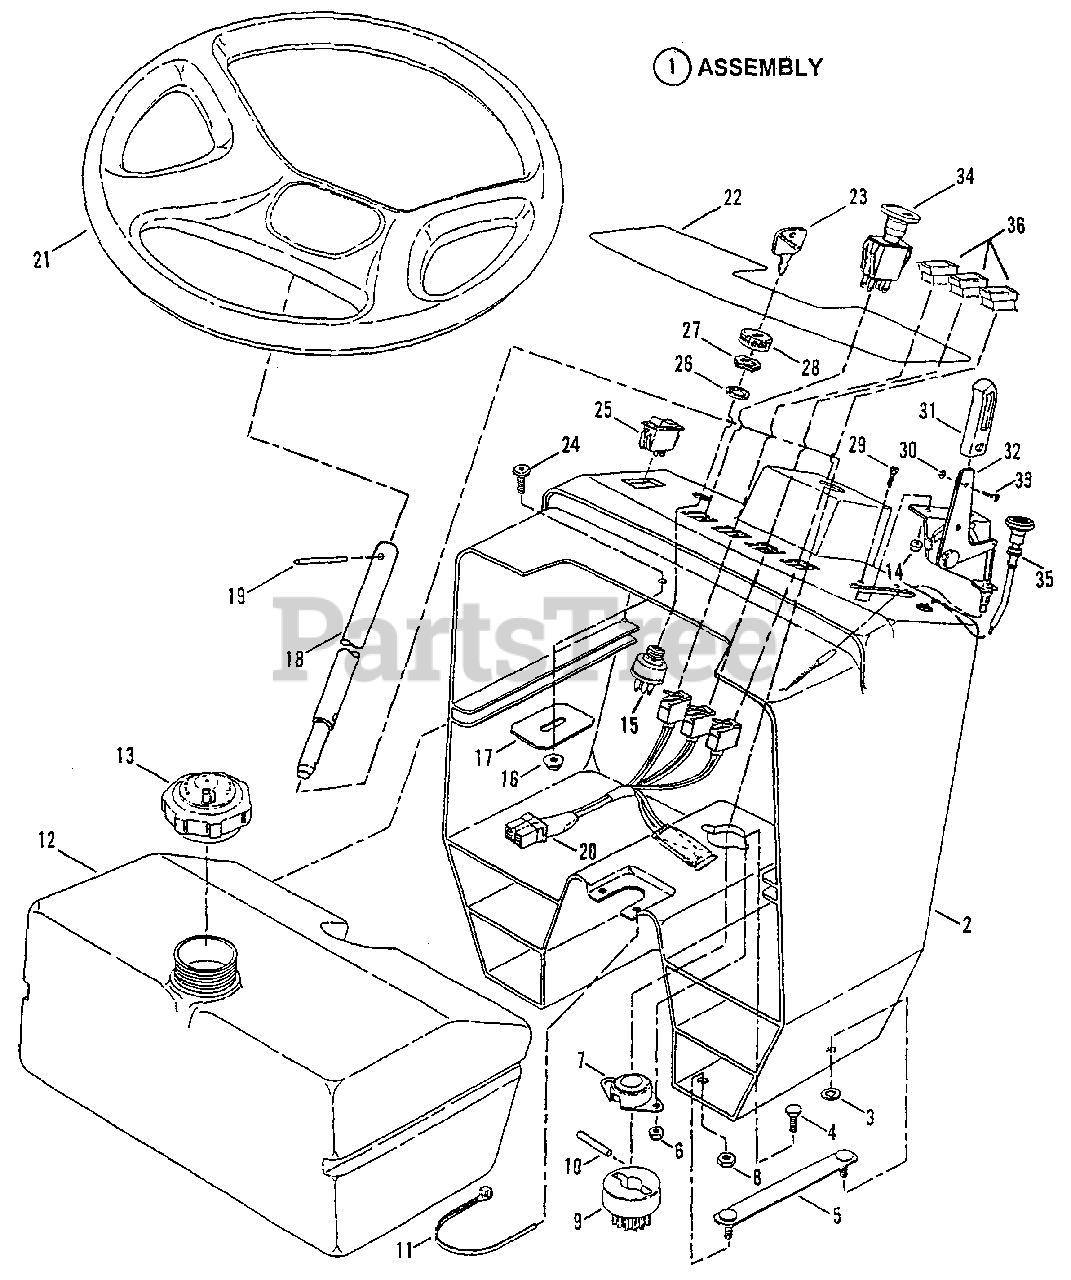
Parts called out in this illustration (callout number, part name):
1	ASSEMBLY, Console
2	CONSOLE
3	RETAINER, 5/16 Bolt
4	SCREW, 1/4-20 x 3/4" Hex Head Cap, Grade 5
5	ASSEMBLY, Strap-Clinch Stud
6	NUT, 1/4-20 Hex Nyloc
7	ASSEMBLY, Flange Bearing
8	NUT, 5/16-18 Hex Center Lock, Grade B or 5
9	GEAR, Pinion, Steering Shaft
10	PIN, Dowel, 1/4 x 1-1/4"
11	TIE, Wire
12	ASSEMBLY, Fuel Tank
13	CAP, Fuel Tank
14	NUT, #10-24 Hex Nyloc
15	KEY SWITCH
16	NUT, 5/16-18 Hex Flange Lock
17	BRACKET, Hood Latch Catch
18	SHAFT, Steering
19	ROLL-PIN, 1/4 x 2-1/4"
20	LIGHTS, Indicator
21	STEERING WHEEL
22	DECAL, Console
23	KEY, Switch (With Cover)
24	SCREW, 5/16-18 x 5/8" Truss Head, Torx
25	SWITCH, Lights
27	NUT, 5/8-32 Hex
28	BEZEL
29	SCREW, 010-24 x 5/8" Machine
30	NUT, #8-32 Hex, Grade 2 or 8
31	HANDLE, Throttle Control
32	CONTROL, Throttle
33	SCREW, #8-32 x 3/8" Cross-Recessed, Fillester Head, Grade 2
34	SWITCH, PTO
35	CABLE, Choke
36	LENS, Indicator Light
